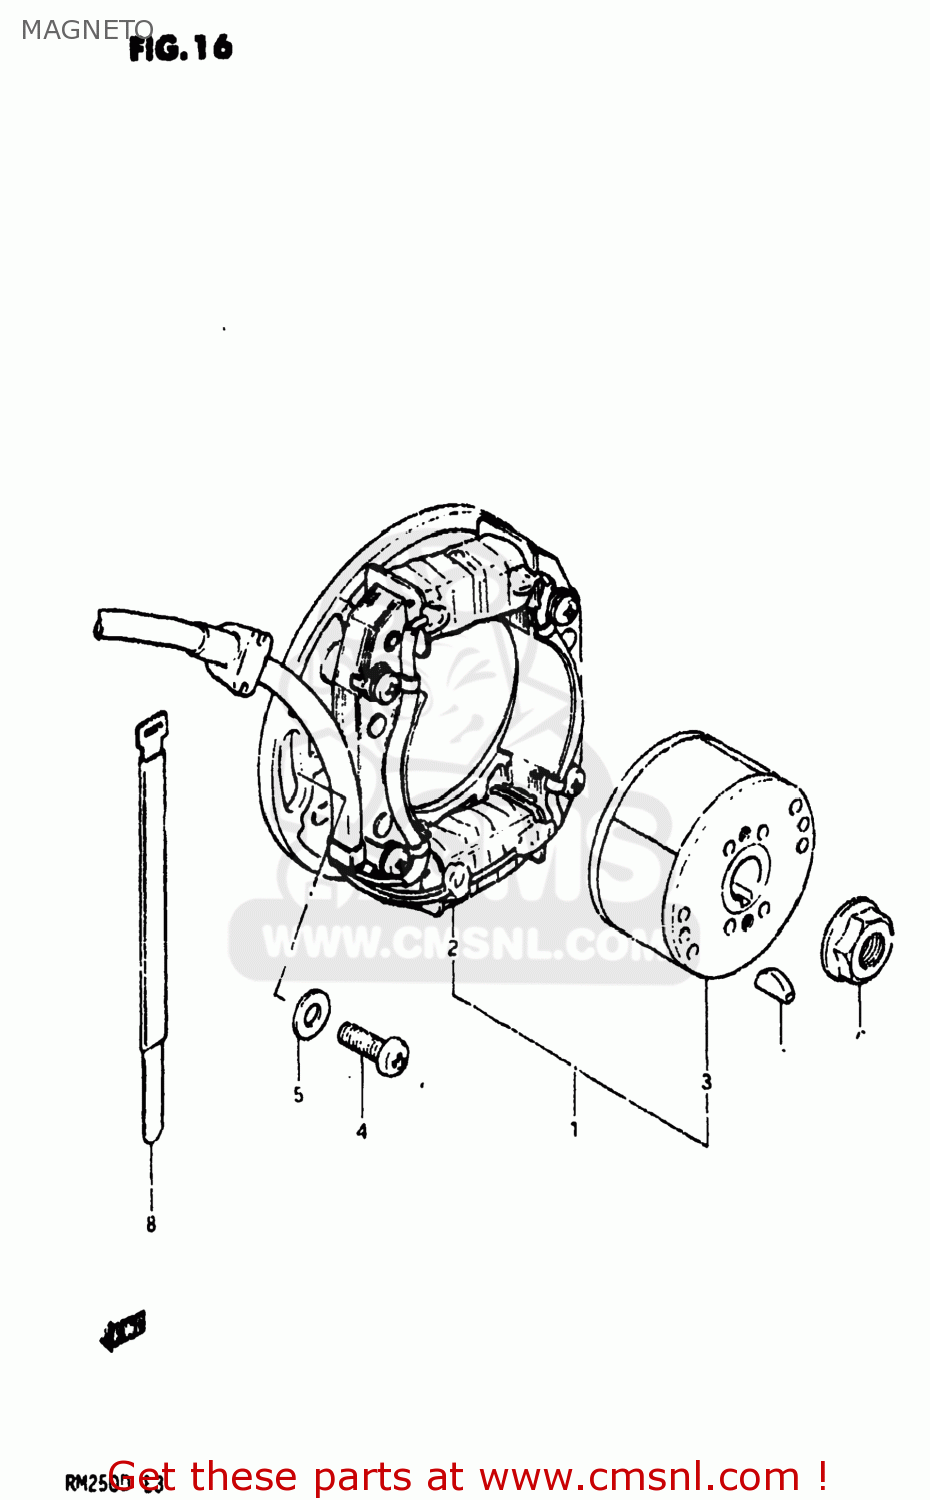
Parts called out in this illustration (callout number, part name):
1	MAGNETO ASSEMBLY
2	STARTER ASSY
3	ROTOR ASSEMBLY
4	SCREW
5	WASHER
6	NUT
7	KEY 4MM
8	CLAMP
